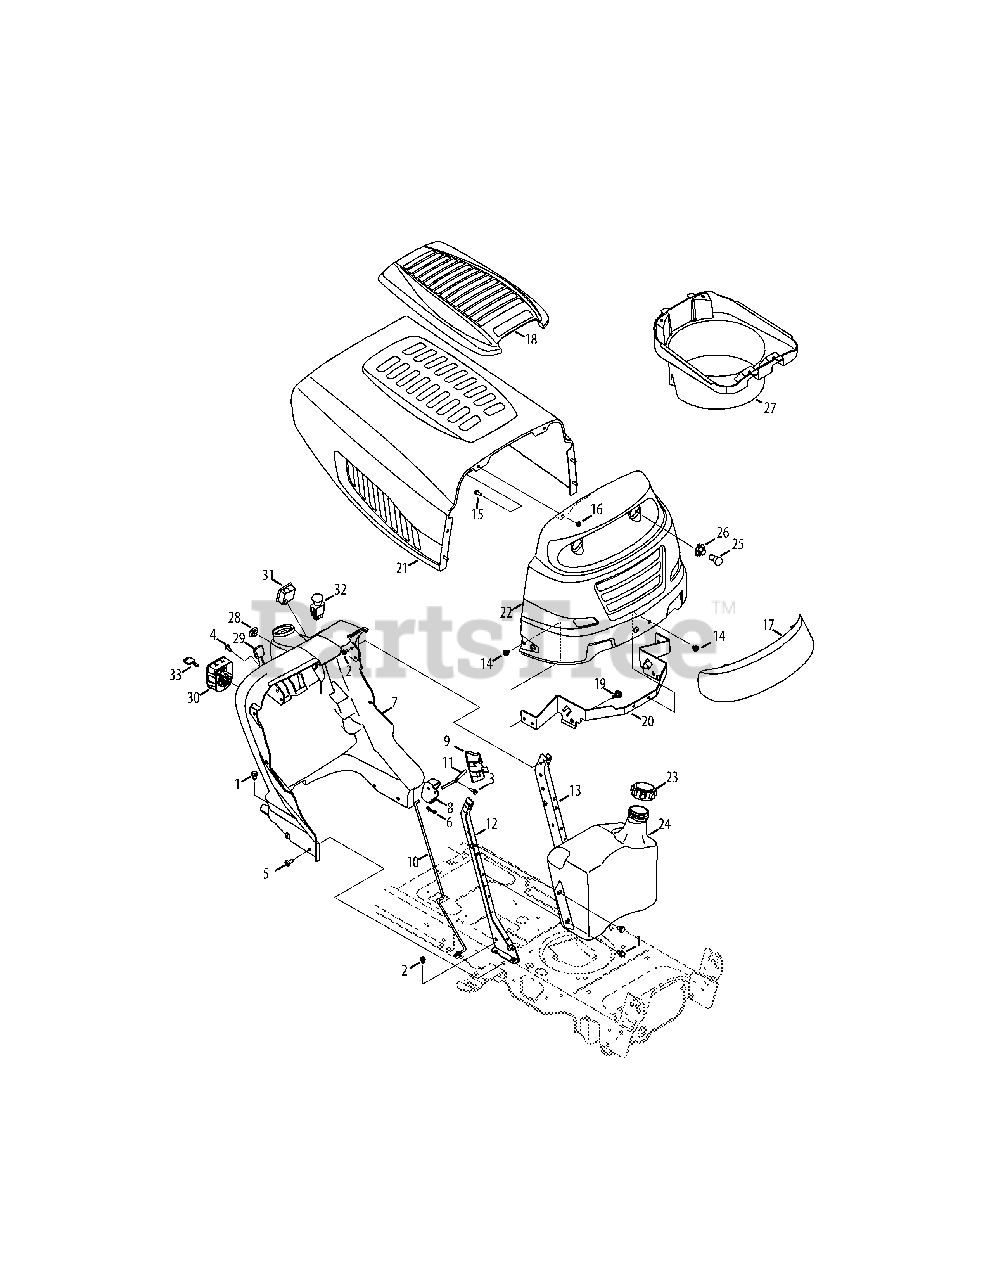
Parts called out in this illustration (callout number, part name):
1	Taptite Screw, 5/16-18:.750
2	Taptite Screw, 1/4-20:0.500
3	Hi-Lo Screw, 1/4-15:0.750
4	Screw, 1/4-14:0.625
5	Taptite Screw, 5/16-18:0.750
6	Bow Tie Cotter Pin
7	Dash Panel
8	Dash Lever
9	Cruise Cover
10	Control Rod
11	Lever
12	RH Support Plate
13	LH Support Plate
14	Taptite Screw, 5/16-18:0.375
15	Hex Screw, 1/4-20:.620
16	Flangelock Nut, 1/4-20
17	Grill Lens
18	Hood Scoop
19	Shoulder Screw, .43X.29:5/16-18
20	Hood Pivot Bracket
22	Grill
23	Fuel Cap
24	Fuel Tank
26	Lamp Socket
28	Choke Plug
29	Throttle/Choke Cable
30	Key Switch Module
31	Hour Meter
32	Electric PTO Switch
